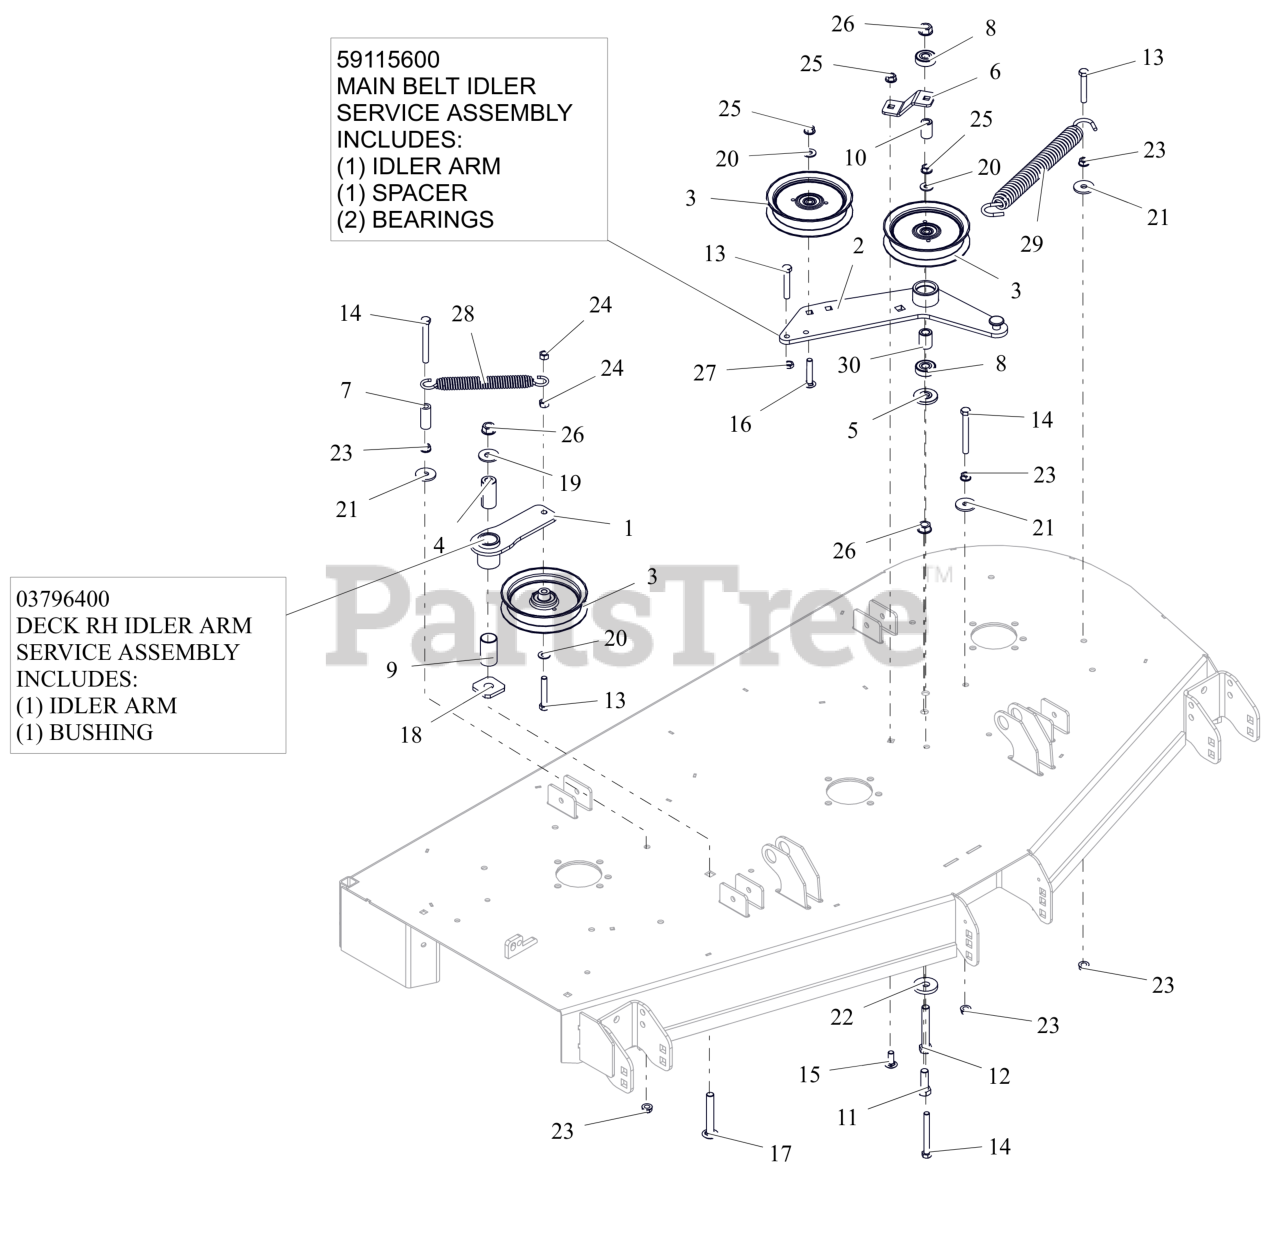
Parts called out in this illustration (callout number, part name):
1	WMT, IDLER ARM - BLACK
1	ASM, IDLER ARM (DECK)
2	WLDMT, DECK PTO IDLR ARM
2	ASSEMBLY, MAIN BELT IDLER
3	IDLER, FLAT 5.00"
4	BSHG, SPCR .502X.997X2.03 PM
5	SPACER, IDLER ARM
6	PTO FIXED IDLER MTG BRKT-ORG
7	HOSE, .38 X 1.65
8	BRG-BALL .500X1.38X.437
9	BSHG, 1.00X1.125X1.937
10	BUSHING, SLV .380X.750X1.190
11	BLT,HEX .50-13X1.50 G5 ZCC
12	BLT,HEX .50-13X3.25 G5 ZCC
13	BLT,HEX .38-16X2.25 G5 ZCC
14	BLT, HEX .38-16X3.25 G5 ZCC
15	BLT,RHSSN .38-16X1.00 G5 ZCC
16	BLT,RHSSN.375-16X2.00 G5 ZCC
17	BTL,RHSSN .500-13 X 3.25 G5 ZCC
18	WSHR-FLT .640X1.75X.250
19	WSHR,FLT .563X1.375X.109 ZCC
20	WSHR-FL-STL 0.
21	WSHR,FLT .406X1.375X.135 ZCC
22	WSHR-FL-STL 0.557X1.625X0.25 ZCC
23	NUT, SPNLK-FLG .38-16 G5 ZCC
24	NUT-LK-CTR .38-16 ZC120
25	NUT-LK-CTR-FLG .375-16 GF ZCC
26	NUT-LK-CTR-FLG .500-13 GG ZCC
27	NUT-JAM .375-16 G2 ZCC
28	SPRING, EXTENSION
29	SPRING, EXTENSION
30	SPACER .510 X .75 X 1.1485
